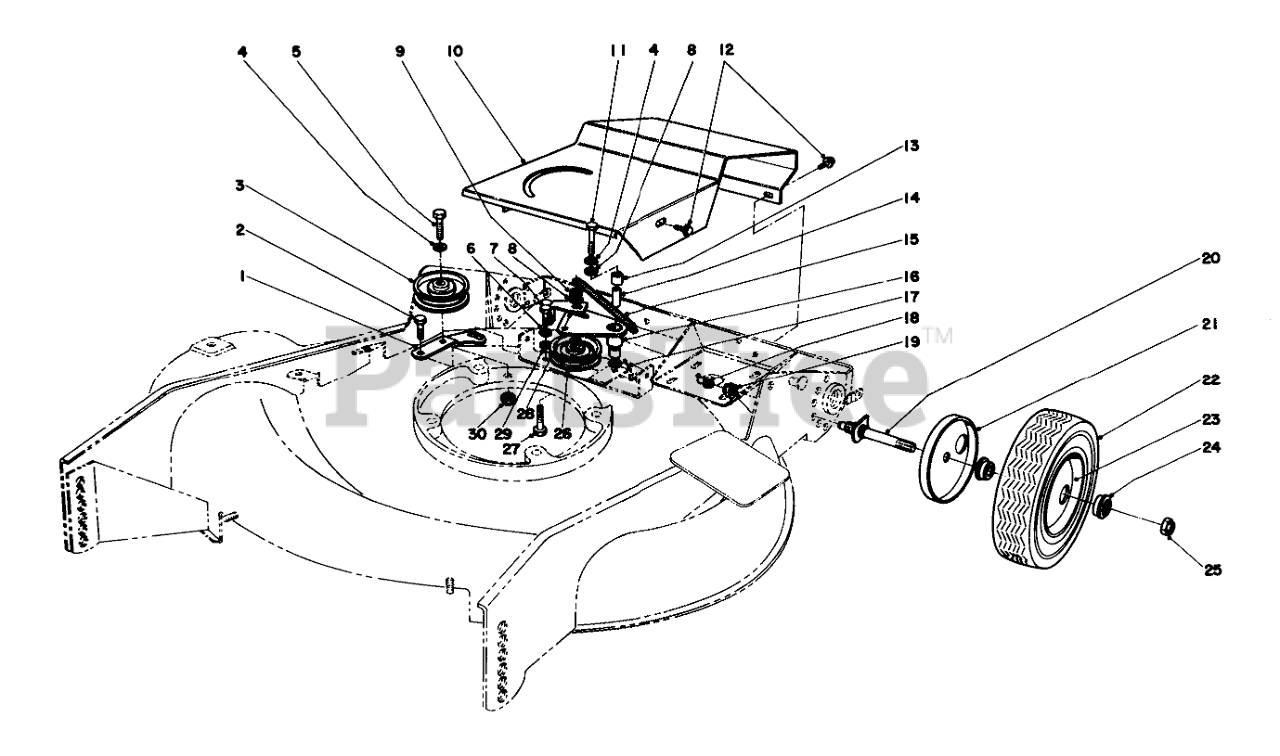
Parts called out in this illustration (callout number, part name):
1	Arm, Auxiliary Idler
2	SCREW-HH
3	PULLEY-IDLER
4	WASHER-LOCK
5	SCREW-HH
6	Lockwasher
7	SCREW-HH
8	WASHER-FLAT
9	Nut
10	Shroud
11	SCREW-HH
12	Screw
13	BUSHING
14	ROLLED SPACER
15	IDLER SPRING
16	Idler Arm (Incl. Ref. #14)
17	PIN-COTTER
18	GREASE FITTING
19	NUT-LOCK, NI
20	Spindle (Incl. Ref. #21)
21	WHEEL COVER
23	REAR WHEEL & TIRE ASM
24	BEARING-BALL
25	Nut
26	IDLER PULLEY R
27	Screw
29	WASHER-PLAIN
30	Nut
